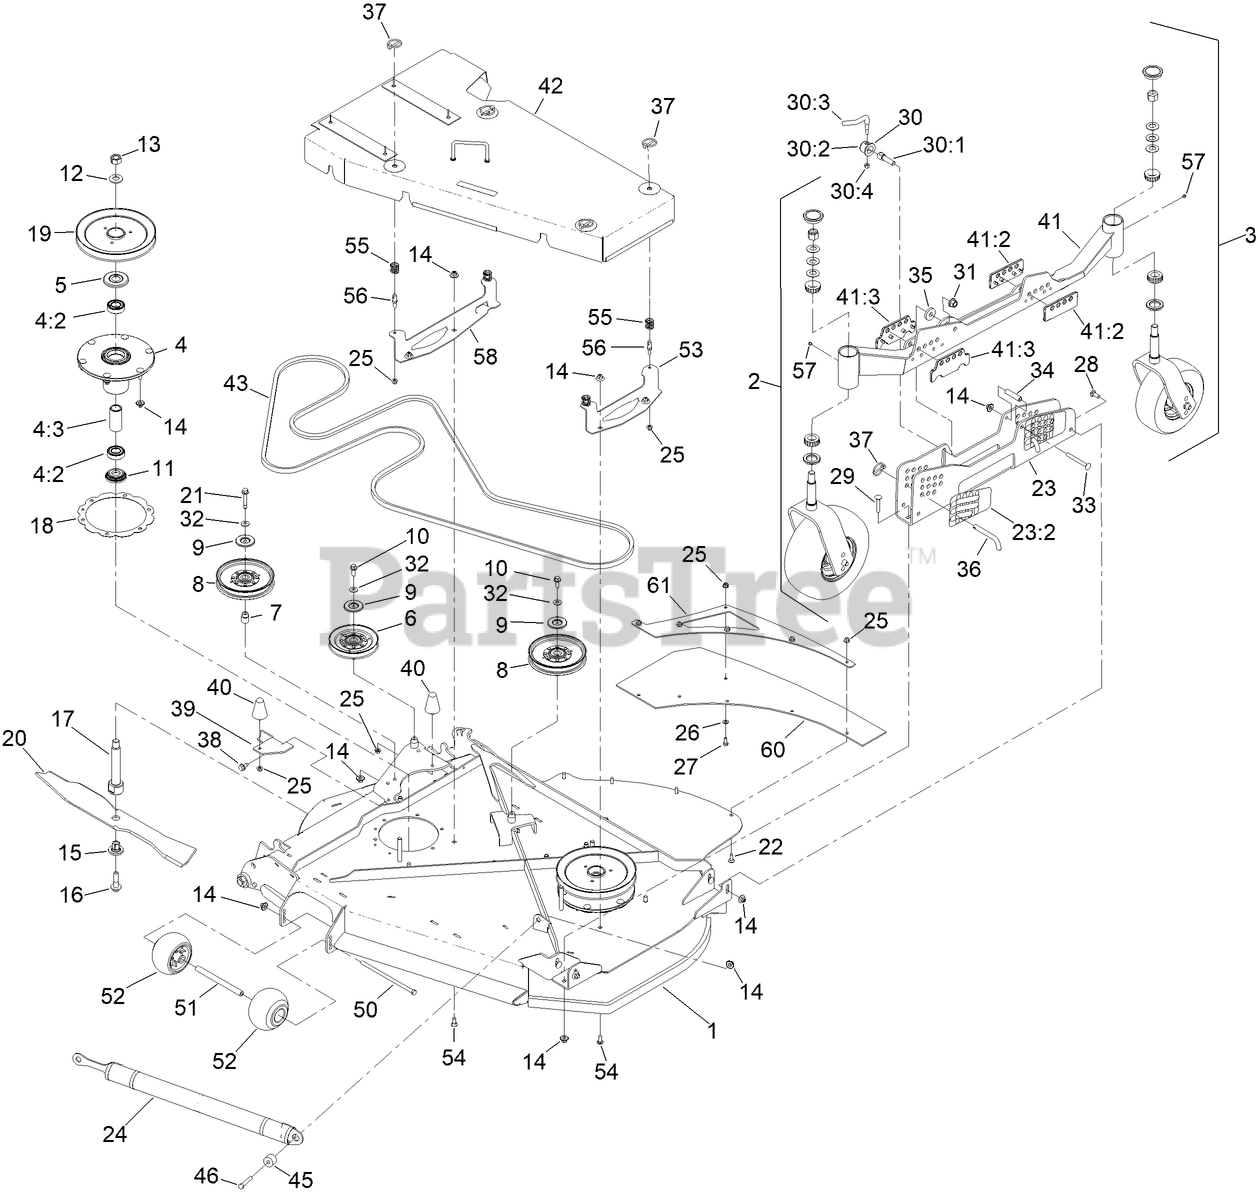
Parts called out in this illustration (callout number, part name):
1	ASM-DECK, LH WING [W/DECALS]
2	CASTER WHEEL ASM
3	REAR CASTER WHEEL ASM
4	SPINDLE ASM
4:2	BEARING-BALL
4:3	SPACER-BEARING
5	GUARD-BEARING, TOP
6	IDLER-V
7	BUSHING-IDLER
8	IDLER-PULLEY
9	SHIELD-DUST
10	SCREW-HHF
11	GUARD-BOTTOM
12	WASHER
13	NUT-HEX
14	NUT-FLANGE, NI
15	BUSHING-HEX
16	SCREW-SEMS
17	SHAFT-SPINDLE
18	RING-SPACER, HOUSING
19	SHEAVE-DRIVE, BLADE
20	BLADE-24.50 MULCH
21	SCREW-HHF W/ PATCH
22	BOLT-CARR
23	ASM-CHANNEL, HOC LH
23:2	DECAL-HEIGHT OF CUT-LH
24	ASM-WEIGHT-TRANSFER-SPRING
25	NUT-HF, NI
26	WASHER-PLAIN
27	SCREW-HH
28	BOLT-CARR
29	SCREW-CARR
30	LEVER ASM
30:1	SCREW-LOCK
30:2	CAP-LOCK
30:4	NUT-LOCK, NI
31	NUT-LOCK
32	WASHER-BELLEVILLE
33	SCREW-CARR
34	SPACER
35	WASHER
36	PIN-HOC
37	PIN-LYNCH
38	SCREW-HWH
39	BRACKET-COVER RETAINER
40	BUMPER-RUBBER
41	ASM-LH GAUGE WHEEL ARM
41:2	PLATE-GUIDE, REAR
41:3	PLATE-GUIDE, FRONT
42	ASM-BELT SHIELD
45	BUSHING-LIFT SPRING
46	SCREW-HH
50	SCREW-HH
51	SPACER-WHEEL
52	ROLLER-SCALP, ANTI
53	BRACKET-SHIELD MOUNT, OUTER
54	BOLT-CARR
55	SPRING
56	PIN, SPRING
58	BRACKET-SHIELD MOUNT, OUTER LONG
60	GUARD-LH REAR WING
61	SUPPORT-LH REAR GUARD
